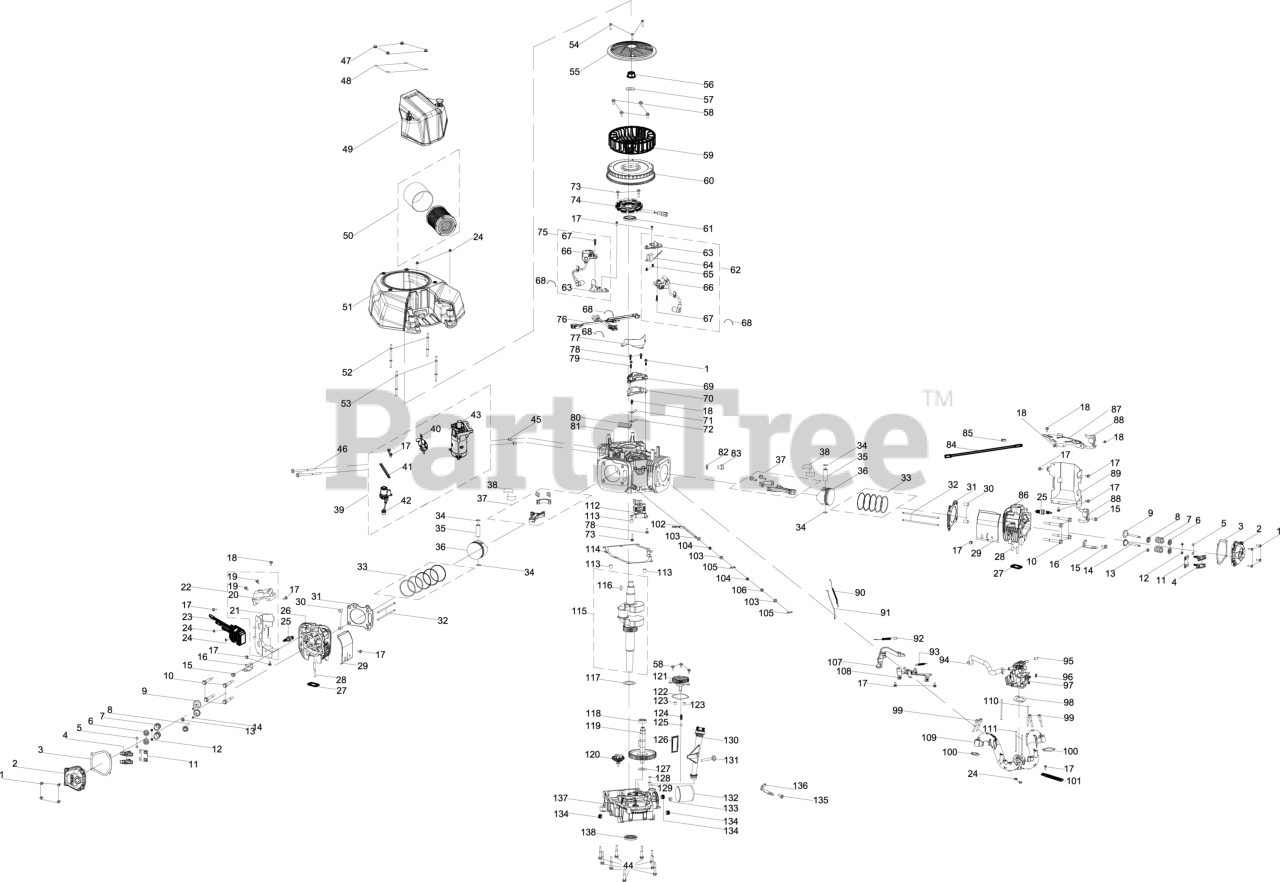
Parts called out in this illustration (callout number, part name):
1	BOLT M6x22
2	VALVE COVER
3	VALVE COVER GASKET
4	ROCKER ARM ASSEMBLY
5	EXHAUST VALVE ADJUSTER
6	VALVE SPRING SEAT
7	VALVE SPRING
8	VALVE SPRING RETAINER
9	INTAKE VALVE
10	BOLT M10x1.25x87
11	PUSH ROD GUIDE
12	VALVE CAP
13	INTAKE VALVE SEAL
14	EXHAUST VALVE
15	BOLT M8x16
16	LIFT HOOK
17	BOLT M6x12
18	BOLT M6x10
19	BOLT M6x10
20	FLYWHEEL SHROUD (LH)
21	CYLINDER HEAD BAFFLE (LH)
22	CYLINDER HEAD BAFFLE (LH)
23	EFI REGULATOR 9Q78
24	NUT M6
25	SPARK PLUG (F6RTC/RN11YC/BPR6ES)
26	CYLINDER HEAD - LH
27	EXHAUST GASKET
28	STUD M8 X 34
29	Shroud
30	DOWEL PIN 12x20
31	CYLINDER HEAD GASKET
32	PUSH ROD
33	PISTON RIN SET
34	PISTON PIN SNAP RING
35	PISTON PIN
36	PISTON ASSEMBLY
37	CONNECTING ROD
38	CONNETING ROS BEARING
39	Electric Starter
40	Starter Relay Support
41	SUPPORT CLAMP
42	Starter Relay
43	ELECTRIC STARTER
44	BOLT M8x48
45	DOWEL PIN
46	BOLT M8x110
47	ACORN NUT
48	WASHER
49	AIR FILTER COVER ASSEMBLY Q78
50	Air Filter Element
51	SHROUD ASSEMBLY
54	SELF TAPPING BOLT 5.5x25
55	DEBRIS SHIELD
56	NUT M20x1.5
57	WASHER 20.5 x 5 x 40
58	BOLT M6-1 x 18
59	COOLING FAN
60	FLYWHEEL
61	OIL SEAL 38 x 58 x 8
62	Trigger Ignition Coil
63	he Trigger Support
64	Trigger
65	Bolt, M5×12
66	Ignition Module
67	Bolt, M5×20
68	CABLE TIE 3x150
69	BEATHER COVER
70	BREATHER COVER GASKET
71	BREATHER REED BRACKET
72	BREATHER REED ASSEMBLY
73	BOLT M6x25
74	Charging Coil
75	Trigger Ignition Coil
76	Wire Harness
77	Wire Harness Bracket
78	BOLT M6x16
79	BOLT M6x28
80	BREATHER FILTER SCREEN
81	CRANKCASE
82	WASHER 20.5X1.5X18
83	BOLT M10x1x10
84	TEMPERATURE SENSOR
85	TEMPERATURE SENSOR CLIP
86	CYLINDER HEAD - RH
87	Shroud, Left
88	MOUNTING BRACKET
89	Cylinder Head Baffle
90	GOVERNOR SPRING 9Q78
91	THROTTLE LINK
92	GOVERNOR SPRING
93	GOVERNOR SPRING - SECONDARY
94	Breather Hose
95	RUBBER CAP
96	THROTTLE LINK CLIP
97	THROTTLE BODY
98	THROTTLE BODY GASKET
99	BOLT M8x50
100	INTAKE MANIFOLD GASKET 9Q78
102	GOVERNOR ARM ROD
103	FLAT WASHER 8.5X15.8X2
104	NEEDLE BEARING 8X12X10
105	GOVERNOR SHAFT CLIP
106	GOVERNOR SEAL
107	Governor Lever
108	Governor Gear Bracket Assembly
109	INTAKE MANIFOLD
110	Stud, M6×35
111	Stud, M6×46
112	ROACKER ARM
113	PIN 8X12
114	CRANKCASE GASKET
115	CRANKSHAFT ASSEMBLY
116	WOODRUFF KEY
117	WASHER - 38.5X1.0X54
118	CAMSHAFT BEARING
119	CAMSHAFT ASSEMBLY
120	GOVERNOR GEAR ASSEMBLY
121	OIL PUMP ASSEMBLY
122	OIL PUMP GASKET
123	DOWEL PIN
124	OIL PUMP SPRING
125	OIL PUMP STEEL BALL
126	OIL PUMP SCREEN
127	THRUST WASHER 17.4X25.9X1.0
128	O-RING 13.2X2.65
129	CRANKCASE OIL PASSAGE PIN
130	DIPSTICK
131	BOLT M6x55
132	ENGINE OIL FILTER
133	OIL FILTER ADAPTER
135	BOLT M8x20
136	LIFT HOOK
137	CRANKCASE COVER
138	OIL SEAL 38 x 58 x 8
